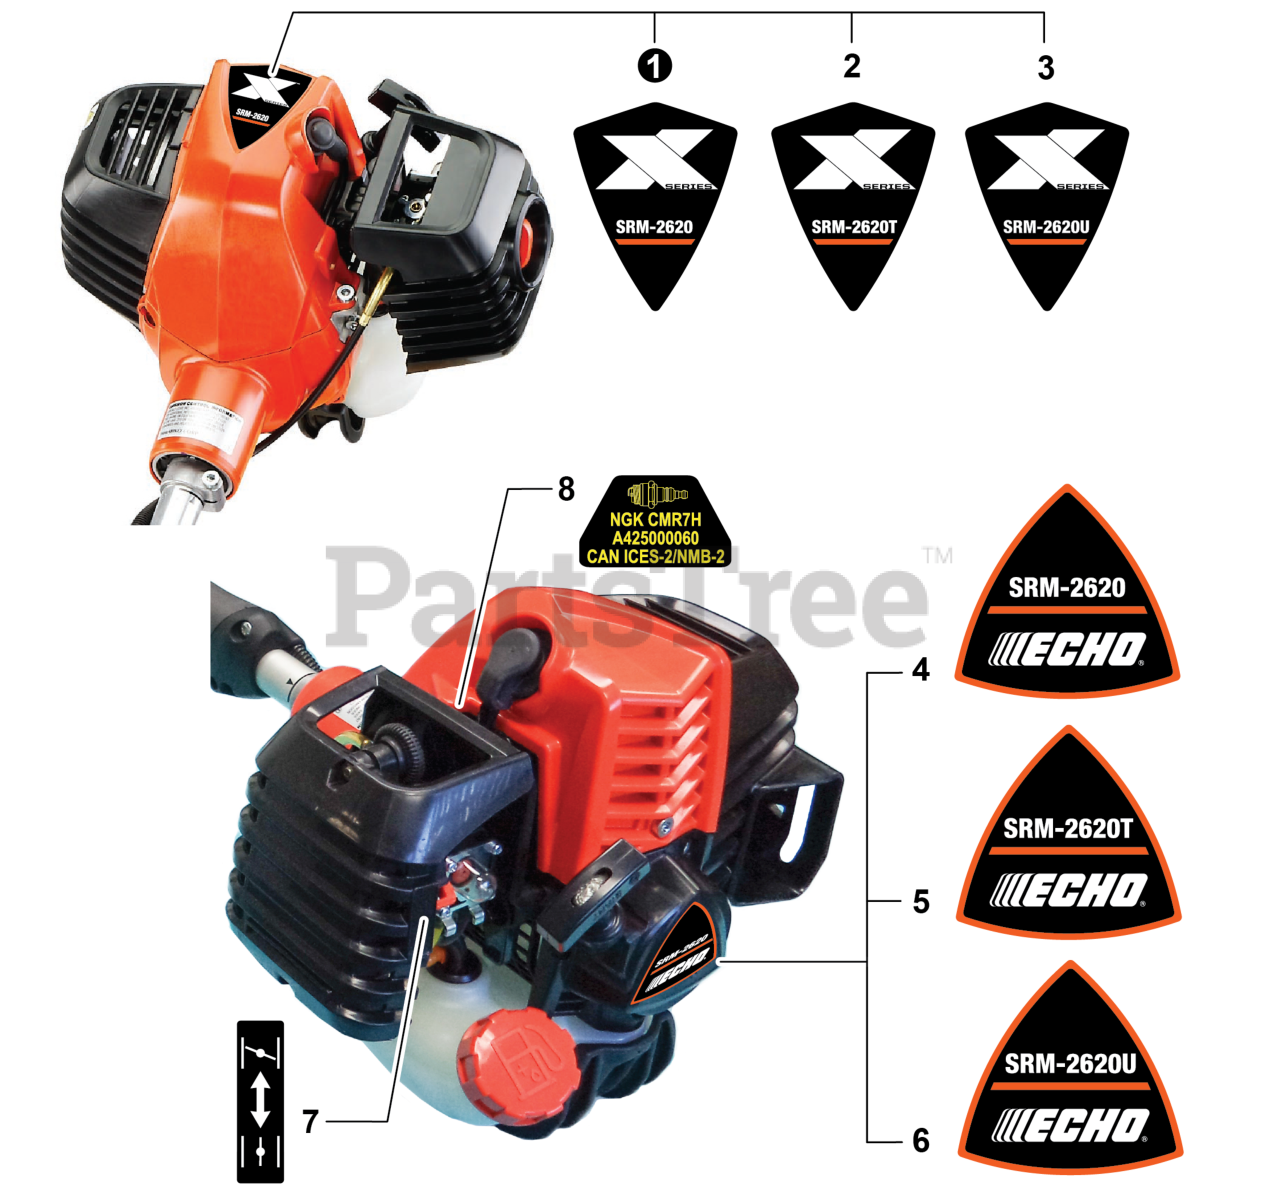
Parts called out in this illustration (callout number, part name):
1	LABEL - MODEL SRM-2620
2	LABEL - MODEL SRM-2620T
3	LABEL - MODEL SRM-2620U
4	LABEL - STARTER - SRM-2620
5	LABEL - STARTER - SRM-2620T
6	LABEL - STARTER - SRM-2620U
7	LABEL - CHOKE
8	LABEL - SPARK PLUG - CMR7H
